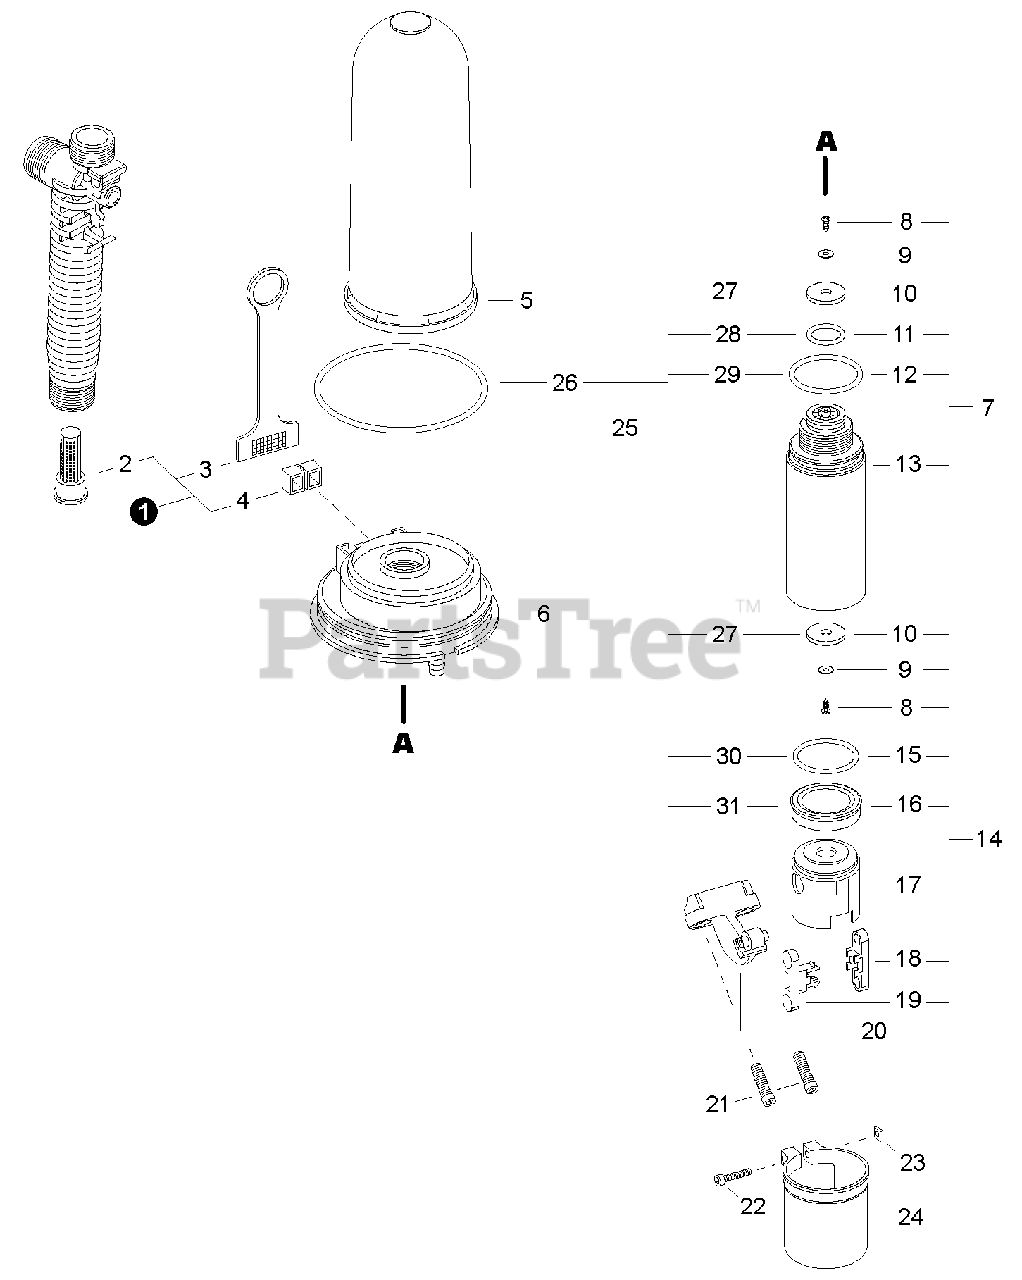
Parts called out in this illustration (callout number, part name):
1	FILTER KIT
2	FILTER, SPRAY GUN
3	FILTER, IN-TANK
4	FILTER, CARTRIDGE
5	CHAMBER, PRESSURE
6	BASE, PRESSURE CHAMBER
7	CYLINDER ASSY
8	SCREW, CYLINDER
9	WASHER
10	SEAL, VALVE
11	O-RING, CYLINDER - SMALL
12	O-RING, CYLINDER - LARGE
13	CYLINDER
14	PISTON ASSY
15	SPRING, SEAL
16	SEAL, PISTON
17	PISTON
18	ROD, CONNECTING - RIGHT
19	ROD, CONNECTING - LEFT
20	LEVER, PIVOT
21	SCREW, LEVER
24	CAP, DUST
25	REPAIR KIT, PUMP
26	O-RING, PRESSURE CHAMBER
27	SEAL, VALVE
28	O-RING, CYLINDER - SMALL
29	O-RING, CYLINDER - LARGE
30	SPRING, SEAL
31	SEAL, PISTON
